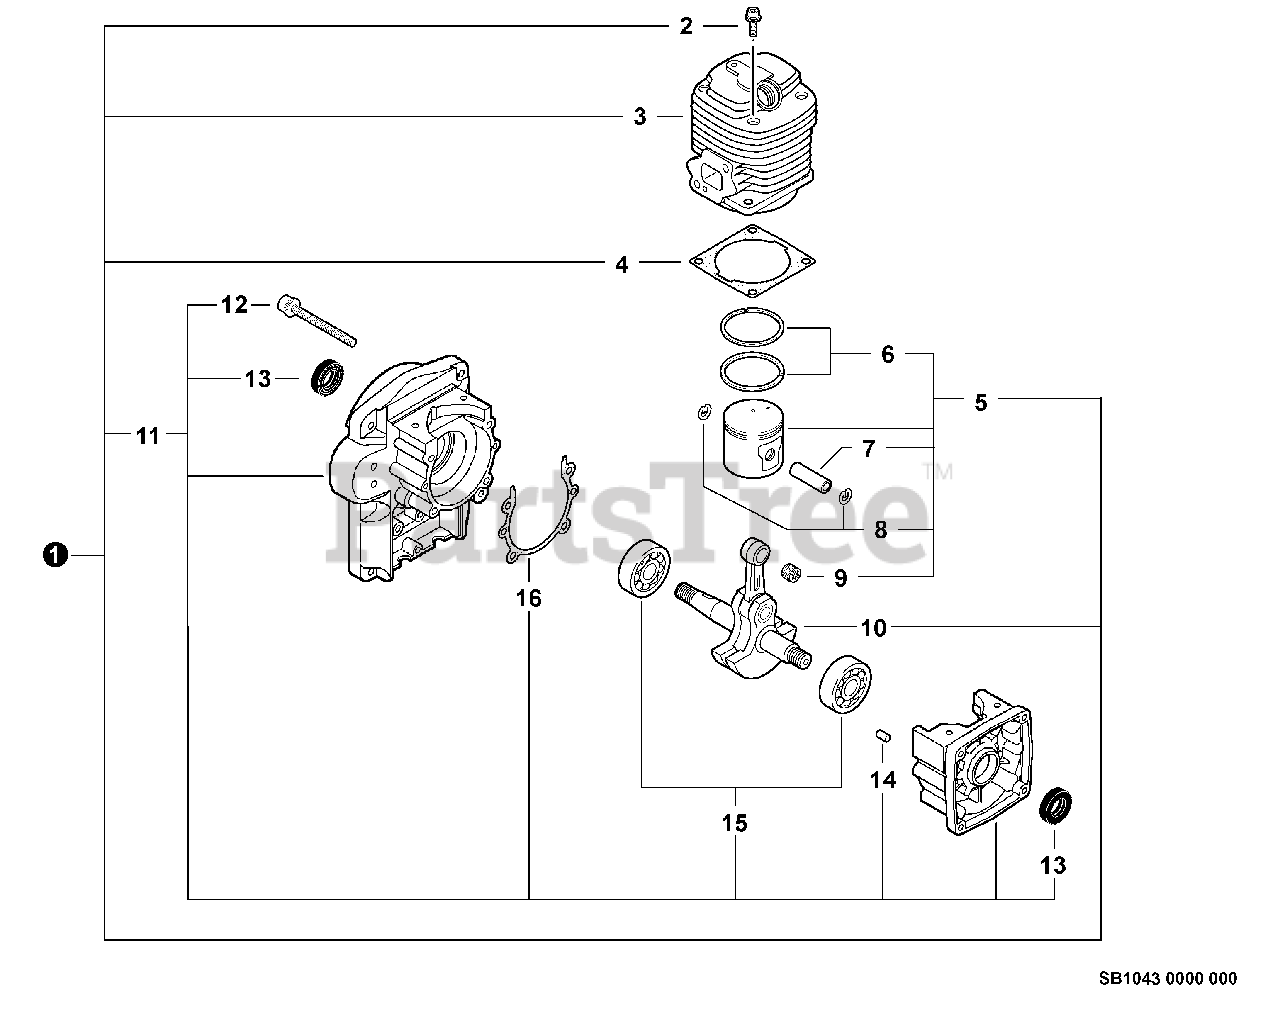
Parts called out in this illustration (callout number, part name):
1	SHORT BLOCK PB-602 603
2	BOLT 5×22
3	CYLINDER
4	GASKET, CYLINDER
5	PISTON KIT
6	RING, PISTON
7	PIN, PISTON
8	RING, SNAP 8
9	BEARING, NEEDLE 10
10	CRANKSHAFT ASSY
11	CRANKCASE KIT
12	SEAL, OIL
13	PIN, LOCATING 4×8
14	BEARING, BALL 6202
15	GASKET, CRANKCASE
16	BOLT 5×40
